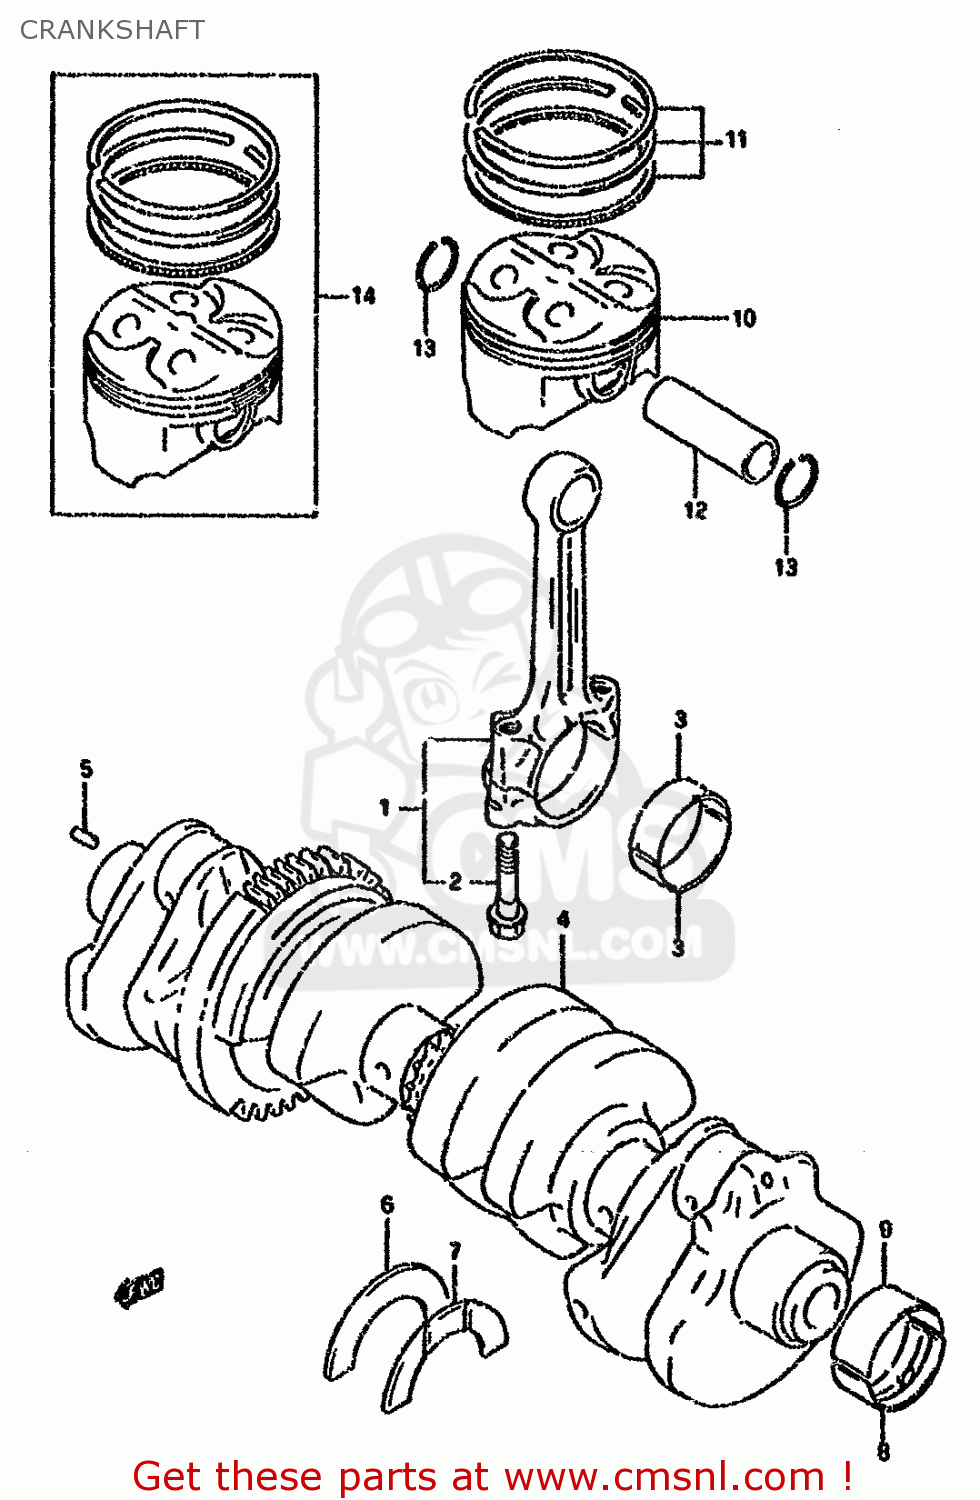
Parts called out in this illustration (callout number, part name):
1	ROD ASSEMBLY,CONNECTING
2	BOLT,CONNECTING ROD
3	BEARING,CRANK PIN
4	CRANKSHAFT SET
5	PIN
6	BEARING,CRANK THRUST(GREEN)
7	BEARING,CRANK THRUST(RED)
8	BEARING,CRANKSHAFT(GREEN)
9	BEARING,CRANKSHAFT(GREEN)
10	PISTON (70.00MM)
11	RING SET,PISTON
12	PIN,PISTON
13	CIRCLIP
14	PISTON SET(OS:0.5)
